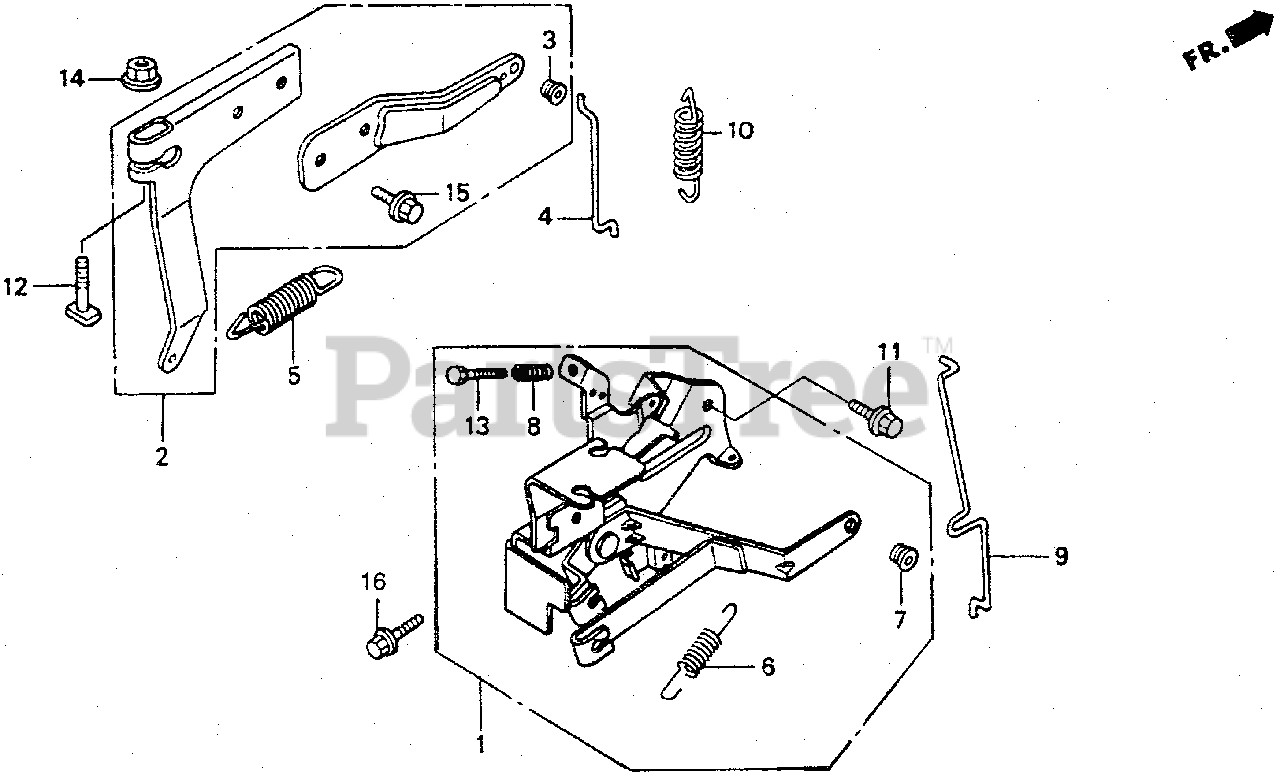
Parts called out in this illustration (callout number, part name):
1	CONTROL
2	ARM, GOVERNOR
3	COLLAR, LEVER
4	ROD, GOVERNOR
5	SPRING, GOVERNOR
6	SPRING, CONTROL LEVER RETURN
7	COLLAR, LEVER
8	SPRING, CONTROL ADJUSTING
9	ROD, CHOKE
10	SPRING, THROTTLE RETURN
11	BOLT, FLANGE (6X14)
12	BOLT, GOVERNOR ARM
13	BOLT, RECESSED (5X34)
14	NUT, FLANGE (6MM)
15	BOLT, FLANGE (6X8)
16	BOLT, FLANGE (8X14)
